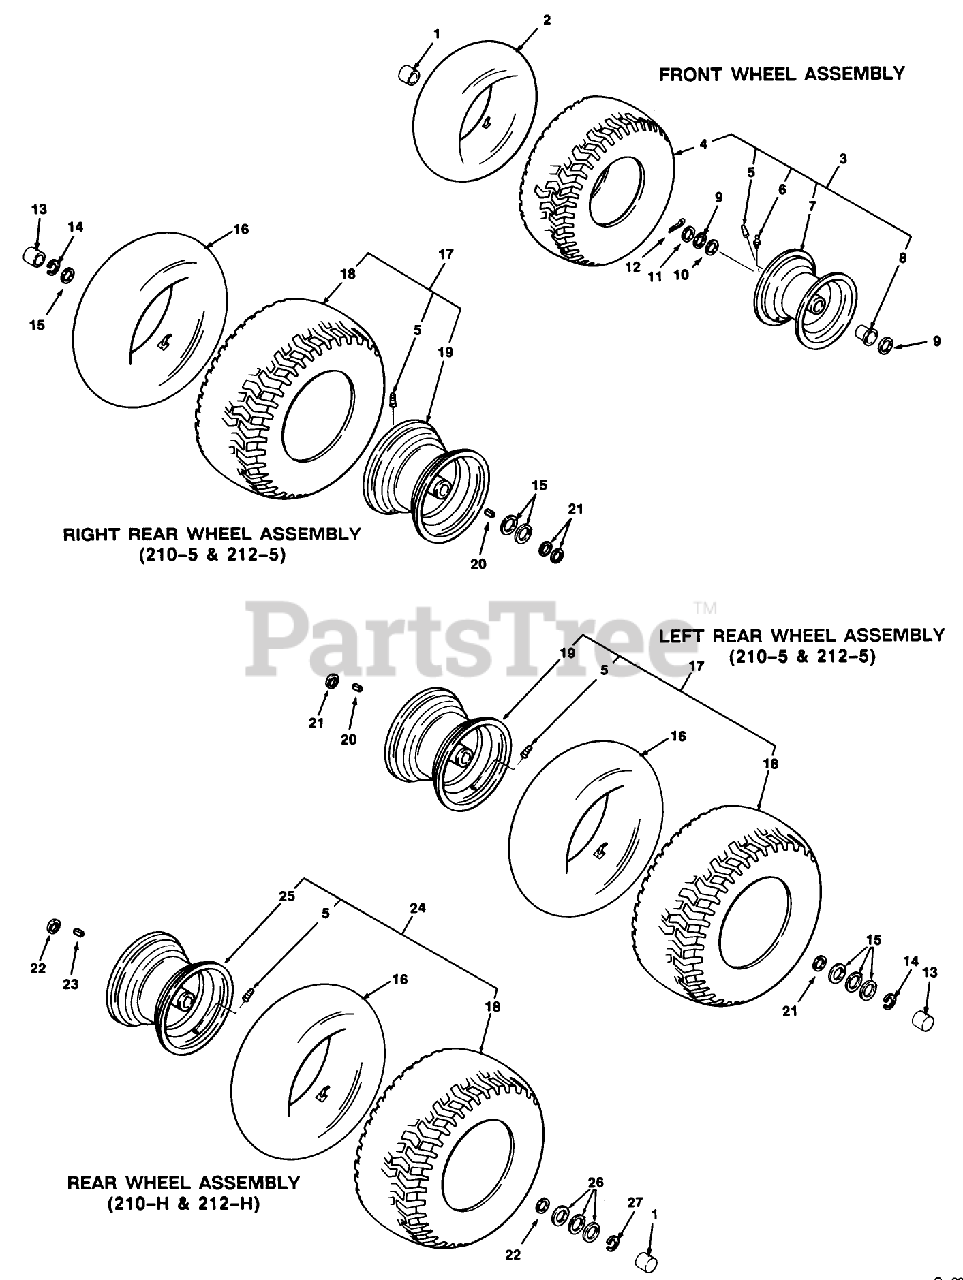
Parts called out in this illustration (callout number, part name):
4	TIRE-15 X 6.00-6
5	VALVE
6	ZERK-GREASE
9	WASHER
10	WASHER-SHIM
11	WASHER-FLAT
12	PIN-COTTER
14	E-RING
15	WASHER-FLAT
17	ASS'Y-WHEEL & TIRE
20	SQ KEY
21	WASHER
22	WASHER
23	KEY-SQUARE
24	ASS'Y-WHEEL & TIRE
25	ASS'Y-WHEEL
26	WASHER-WHEEL
27	RING-RETAINING
